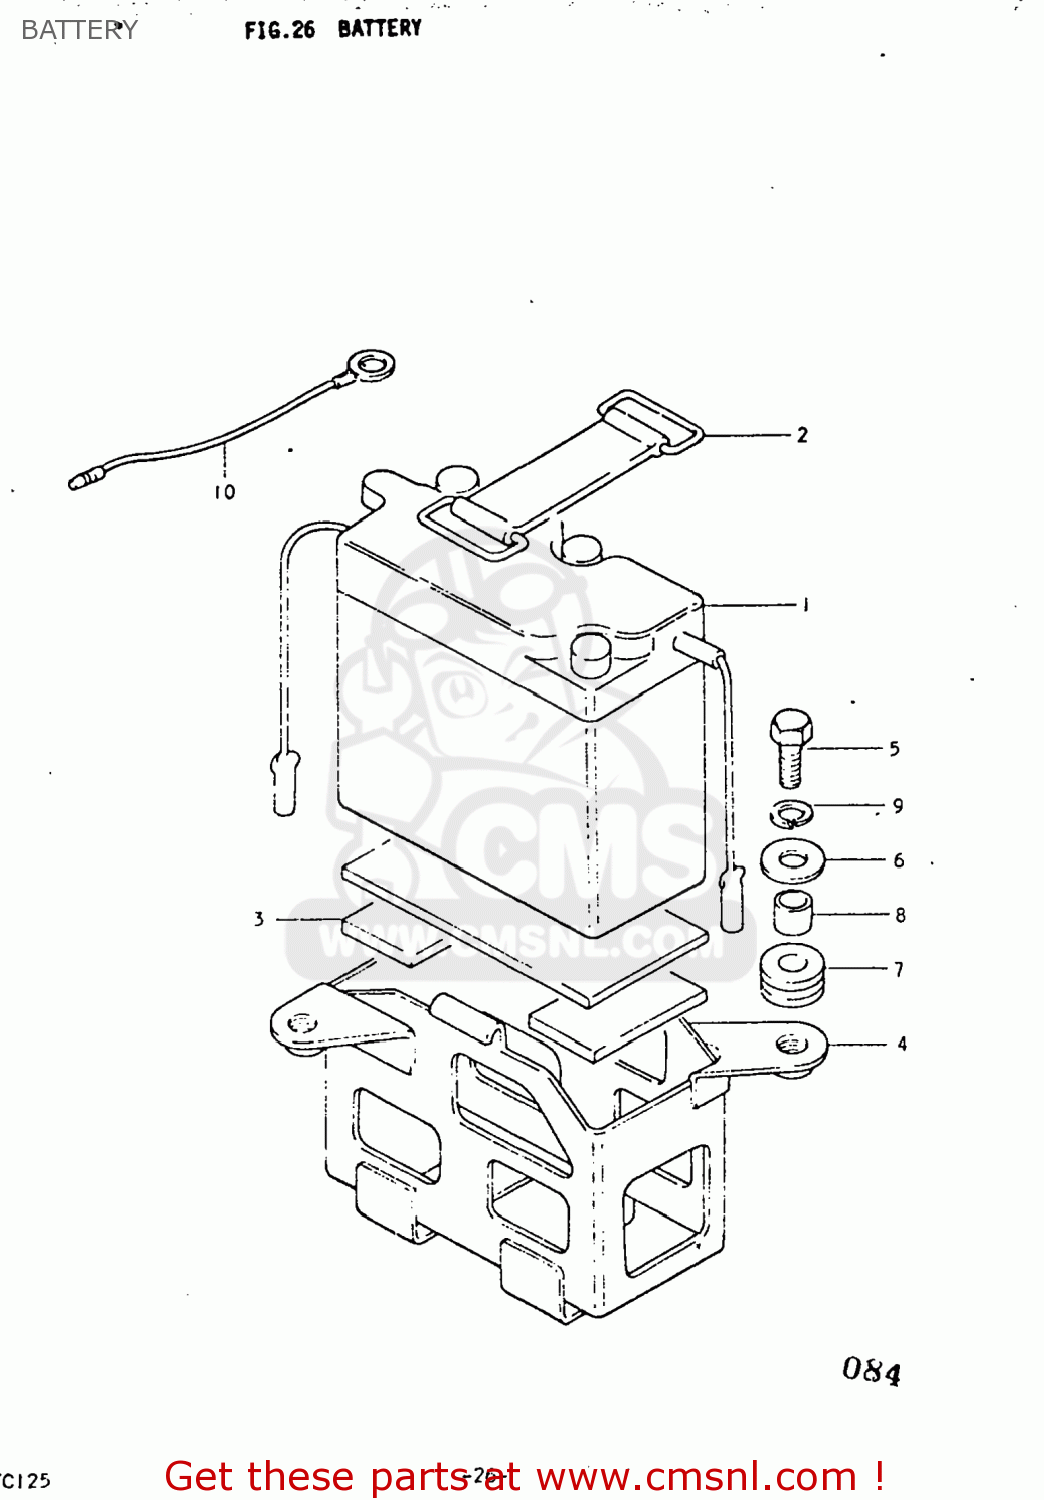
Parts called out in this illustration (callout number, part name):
1	BATTERY(6N4B-2A,6V4.2AH)
2	BAND
3	CUSHION 20X45X6
4	HOLDER,BATTERY
5	BOLT
6	WASHER (6.5X20X1.2)
7	CUSHION
8	SPACER (7X9X7)
9	LOCK WASHER
10	LEAD WIRE
